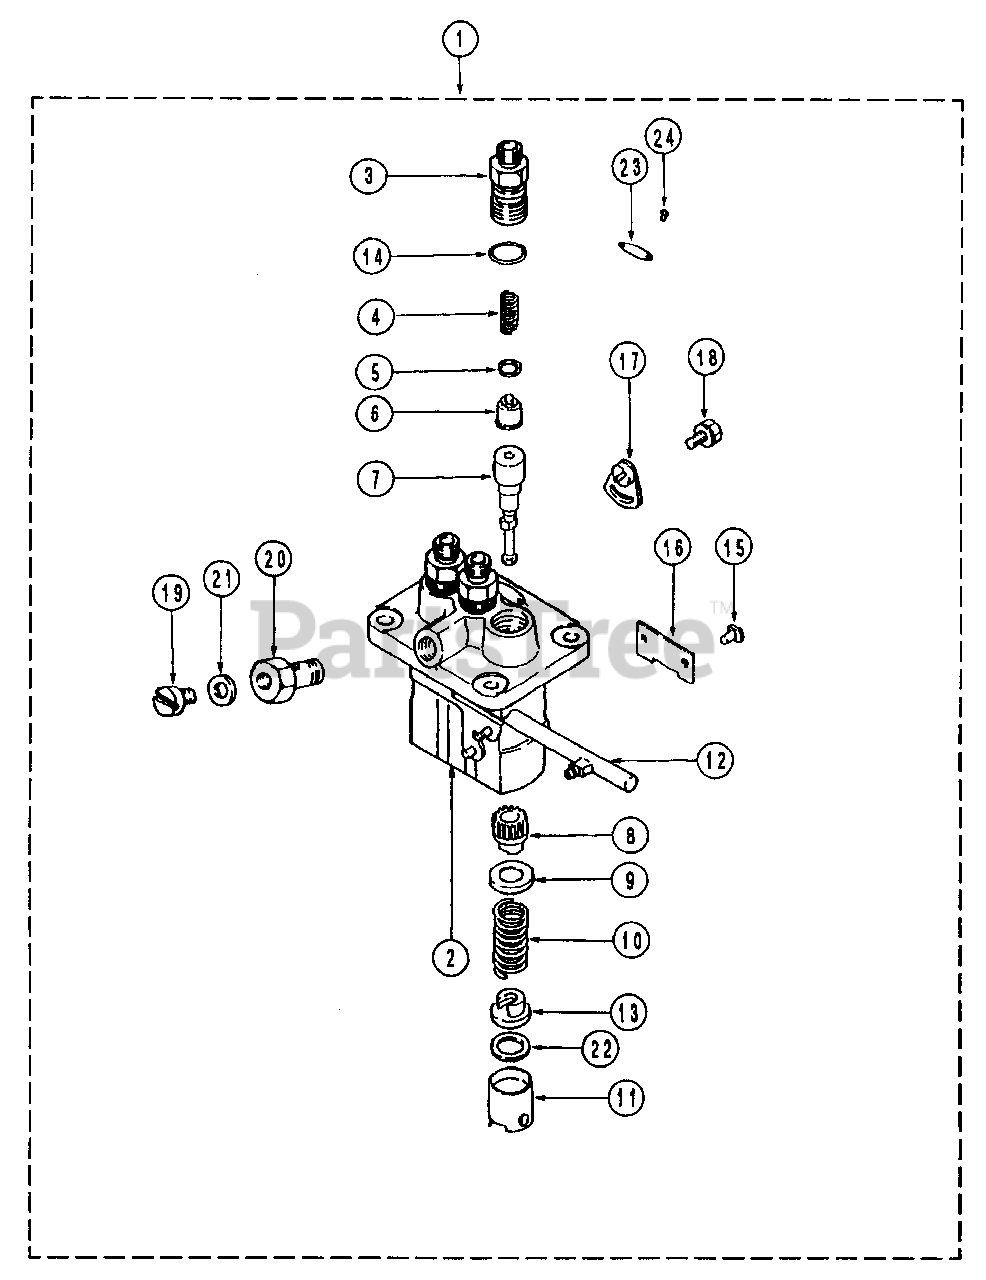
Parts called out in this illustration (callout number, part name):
1	Pump Ass'y., Fuel Inj.
2	Housing Sub Ass'y.
3	Holder, Delivery V.
4	Spring, Delivery V.
5	Gasket, Delivery V.
6	Valve Sub Ass'y.
7	Element Sub Ass'y.
8	Sleeve, Control
9	Seat, Spring, Upper
10	Spring, Plunger
11	Tappet Sub Ass'y.
12	Rack Ass'y., Control
13	Seat, Spring Lower
14	O-Ring
15	Pin, Tappet Guide
17	Plate, Adjusting
18	Bolt, Washer Head
19	Screw, Air Bleeder
20	Screw, Hollow
21	Washer, Pipe Union
22	Plate, Tappet Shim
